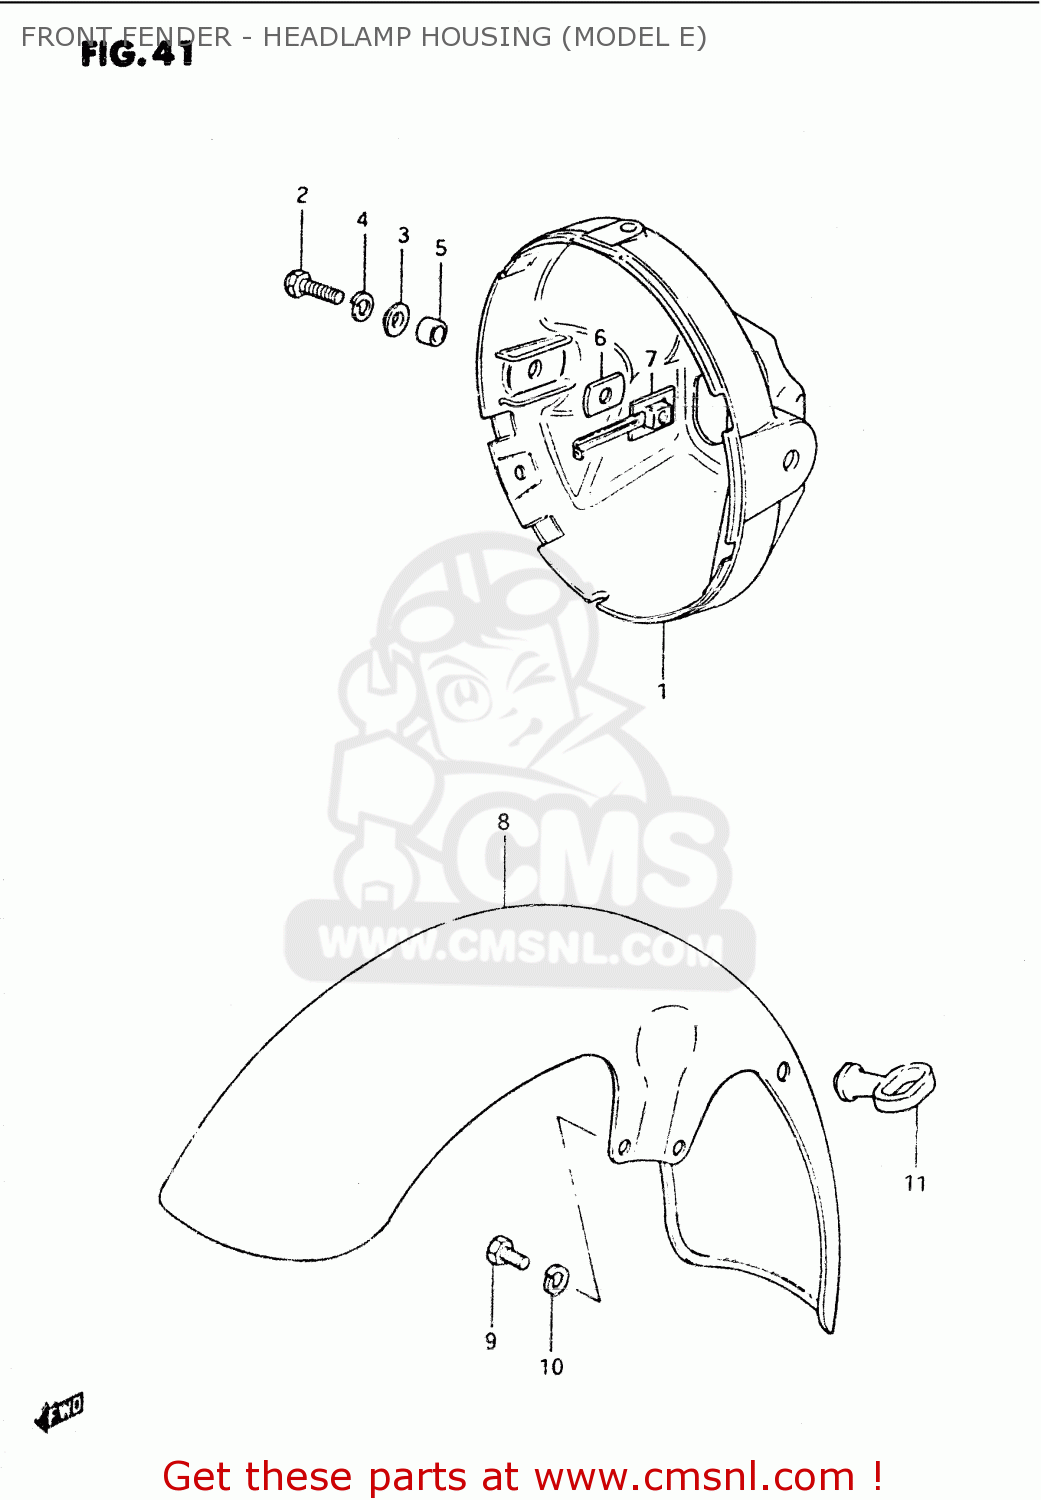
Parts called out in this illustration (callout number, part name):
1	HOUSING,HEADLAMP
2	BOLT
3	WASHER
4	LOCK WASHER
5	SPACER (8.8X12X7)
6	CUSHION
7	PLATE,HEADLAMP HOUSING
8	FENDER, FRONT (GOLD)
9	BOLT
10	LOCK WASHER
11	GUIDE,CABLE
